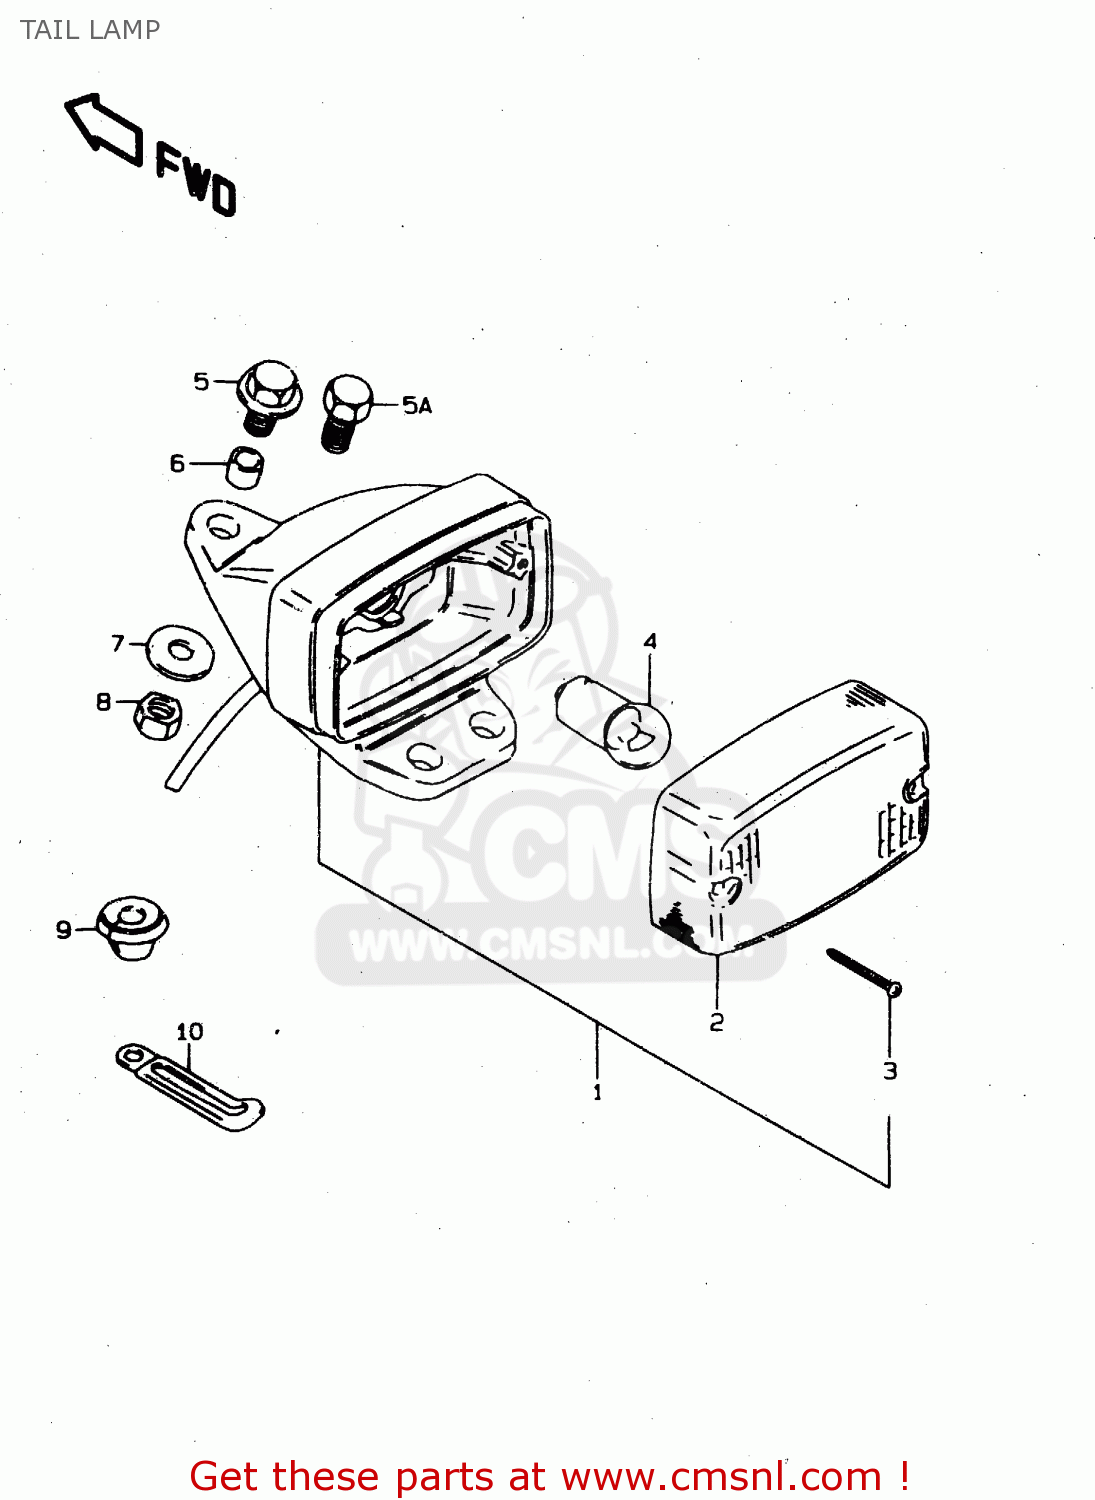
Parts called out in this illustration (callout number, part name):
1	LAMP ASSY,TAIL
2	LENS
3	SCREW
4	BULB(6V5W,TOKAI DENSO)
5	BOLT 6X20
5A	BOLT
6	SPACER(6.5X9X9)
7	WASHER(6.5X20X1.2)
8	NUT 6MM
9	GROMMET
10	CLAMP(L:45)
